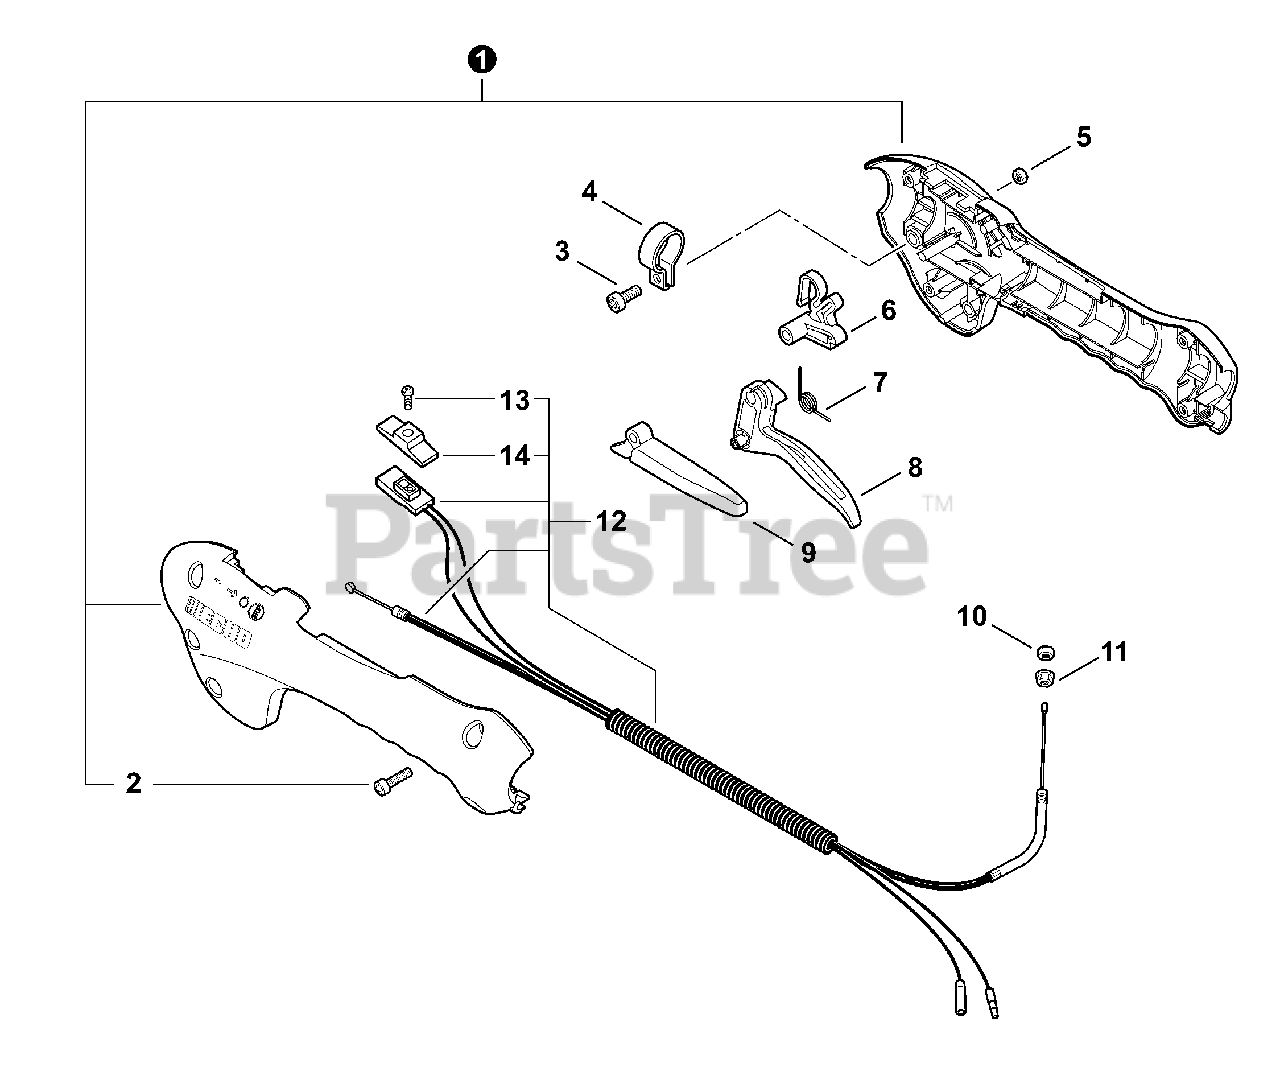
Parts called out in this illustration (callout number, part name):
1	CONTROL HANDLE SET
2	BOLT, TORX 4×16
3	BOLT, TORX 5×16
5	NUT M5
6	LOCKOUT, THROTTLE
7	SPRING, TRIGGER
8	TRIGGER, THROTTLE
9	LEVER, THROTTLE LOCKOUT
11	NUT, FLANGE M6
12	CABLE ASSY, CONTROL
13	SCREW 3×10
14	KNOB, SWITCH - ORANGE
